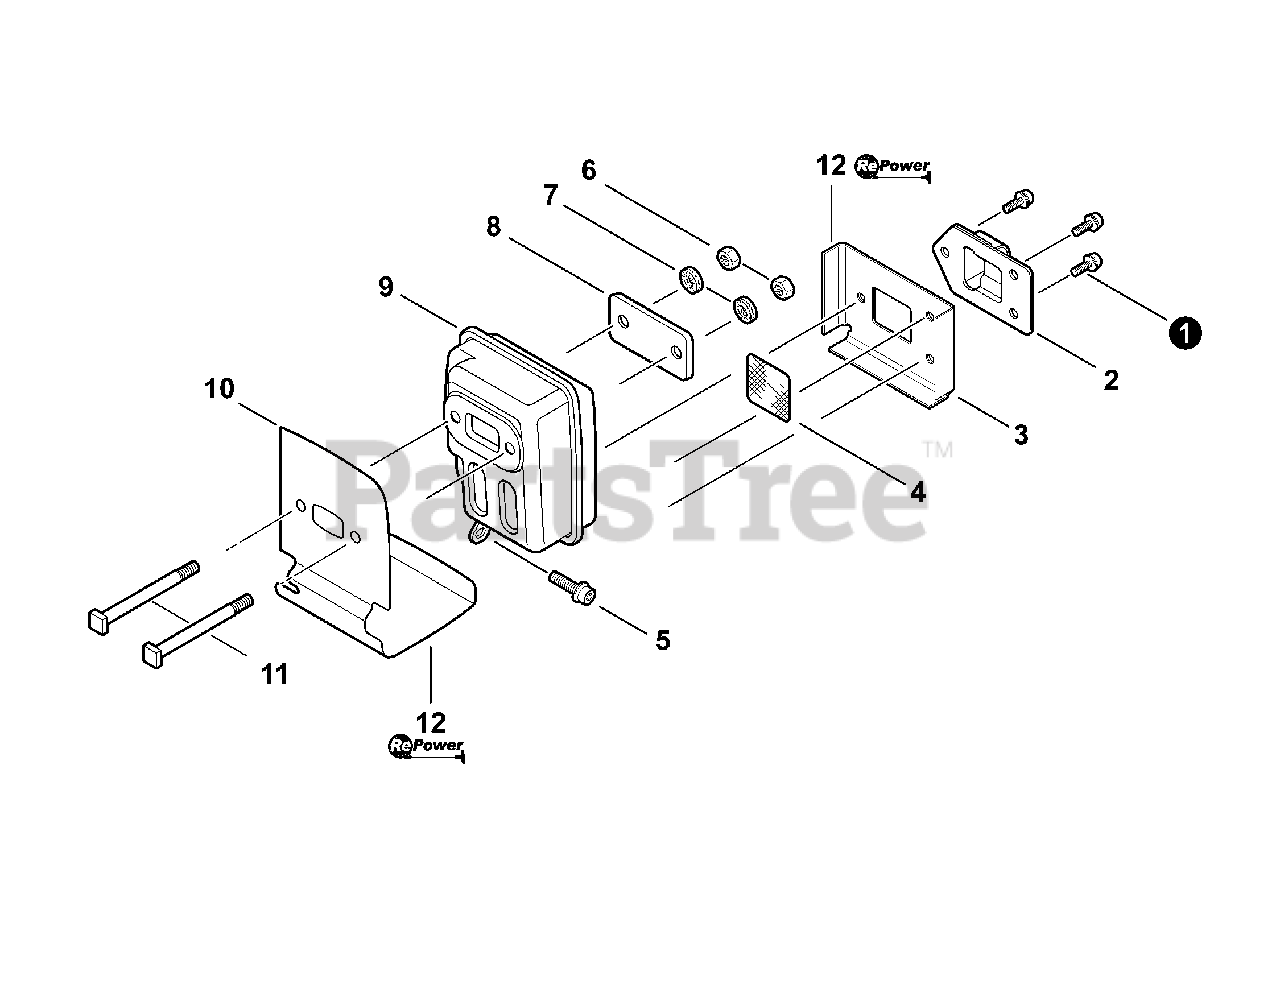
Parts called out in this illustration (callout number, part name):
1	SCREW 4×10
2	GUIDE, EXHAUST
3	GASKET, EXHAUST
4	SCREEN, SPARK ARRESTER
5	BOLT 5×16
6	NUT M5
8	PLATE, EYE
9	MUFFLER
10	HEAT SHIELD, EXHAUST
11	BOLT 5×60
12	GASKET KIT
